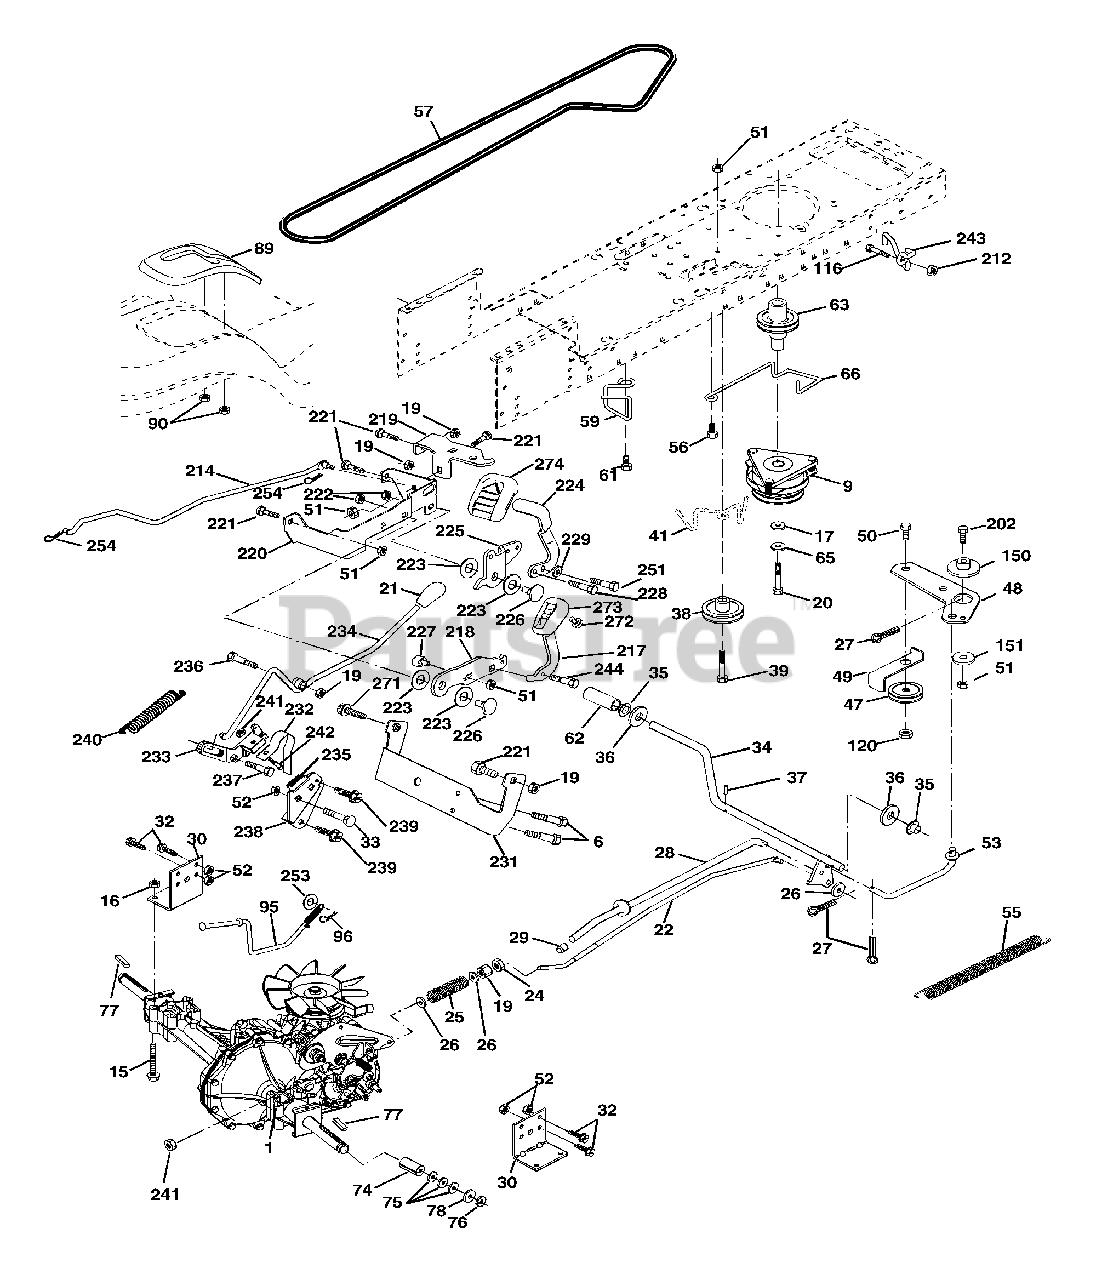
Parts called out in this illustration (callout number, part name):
6	Screw 5/16-18 x 3/4
9	Clutch Elec
15	Bolt Hex Flghd 5/16-18 Gr. 5
16	Nut Lock Hex W/Ins. 5/16-18 Unc
17	Washer 1-1/2 OD x 15/32 ID x .250
19	Nut Lock Hex W/Wsh 3/8-16 Unc
20	Bolt Hex 7/16-20 x 4 x Gr. 5-1.5
21	Knob Custom Control Cruise
22	Rod, Brake
24	Nut, Hex Jam 3/8-16 Unc
25	Spring, Brake Rod
26	Washer
27	Pin Cotter 1/8 x 3/4 CAD.
28	Rod, Parking Brake
29	Cap, Brake, Park
30	Bracket, Transaxle
32	Bolt Hex Hd 5/16-18 Unc x 3/4
33	Bolt Rdhd Sqnk 5/16-18 Unc x 3/4
34	Shaft, Foot Pedal
35	Bearing, Nylon
36	Washer
37	Pin, Roll
38	Pulley, Composite, Flat
39	Bolt Fin Hex 3/8-16 Unc x 3
41	Keeper, Belt Idler Flat
47	Pulley, Idler, V-Groove
48	Bellcrank Clutch Grnd Drw Stl
49	Retainer, Belt
50	Bolt
51	Nut Crownlock 3/8-16 Unc
52	Nut, Crownlock 5/16-18 Unc
53	Link, Clutch
55	Spring, Return, Clutch
57	V-Belt, Ground Drive
59	Keeper, Center Span
61	Screw 3/8-16 x .875
62	Cover, Pedal
63	Pulley, Engine
65	Washer
66	Keeper Belt Engine
74	Spacer, Axle
75	Washer 25/32 x 1-1/4 x 16 Ga.
76	E-Ring
77	Key, Square
78	Washer 25/32 x 1-5/8 x 16 Ga.
89	Console, Shift
90	Nut Self-Thd Wsh-hd 1/4 Zinc
95	Rod Bypass
96	Retainer Spring 1" Zinc/Cad
116	Bolt RDHD SQNK 3/8-16 Unc x 1
120	Nut Lock Flg 3/8-16 Unc
150	Spacer Retainer
151	Washer 13/32 x 2 x 10 Ga.
202	Bolt Carr Sh 3/8-16 x 1-3/4 Gr. 5
212	Nut Hex Flange Lock
214	Link Transaxle
217	Pedal Assy, Reverse, with Pad
218	Arm Control Pedal Reverse
219	Bracket Frest Pdl Ctrl. Hyd
220	Bracket Mtg. Pedal Control
221	Bolt Rdhd Sqnk 3/8-16 Unc x 3/4
222	Nut Crownlock 7/16-14 Unc
223	Washer Nylon 11/16 ID x .060
224	Pedal Forward
225	Arm Control Pedal Forward
226	Bolt Pivot Spacer
227	Cam Reverse Pedal LT
228	Bolt Shoulder 5/16-18
229	Washer Serrated 5/16 x .75
231	Strap Torque
232	Actuator Cruise Disengage
233	Pawl Control Cruise
234	Lever Control Cruise
235	Sector Control Cruise
236	Bolt Shoulder 3/8-16 Unc 1/44
237	Bolt Shoulder 5/16-18
238	Arm Mtg. Cruise Sector
239	Screw Thdrol 5/16 x 1/2
240	Spring Return Cruise Control
241	Nut Centerlock 1/4-20 Unc
242	Bolt Fin Hex 1/4-20 Unc x .75
243	Bracket Anti-Rotation CVX
244	Screw 5/16-18 x 5/8
250	Screw 3/8-16 x .75
253	Washer .3125 x .615 x 16 Ga.
254	Clip Retainer
272	Screw, 5/16-18 x 1/2 TT
273	Pad, Reverse Pedal
274	Cover Pedal Forward
